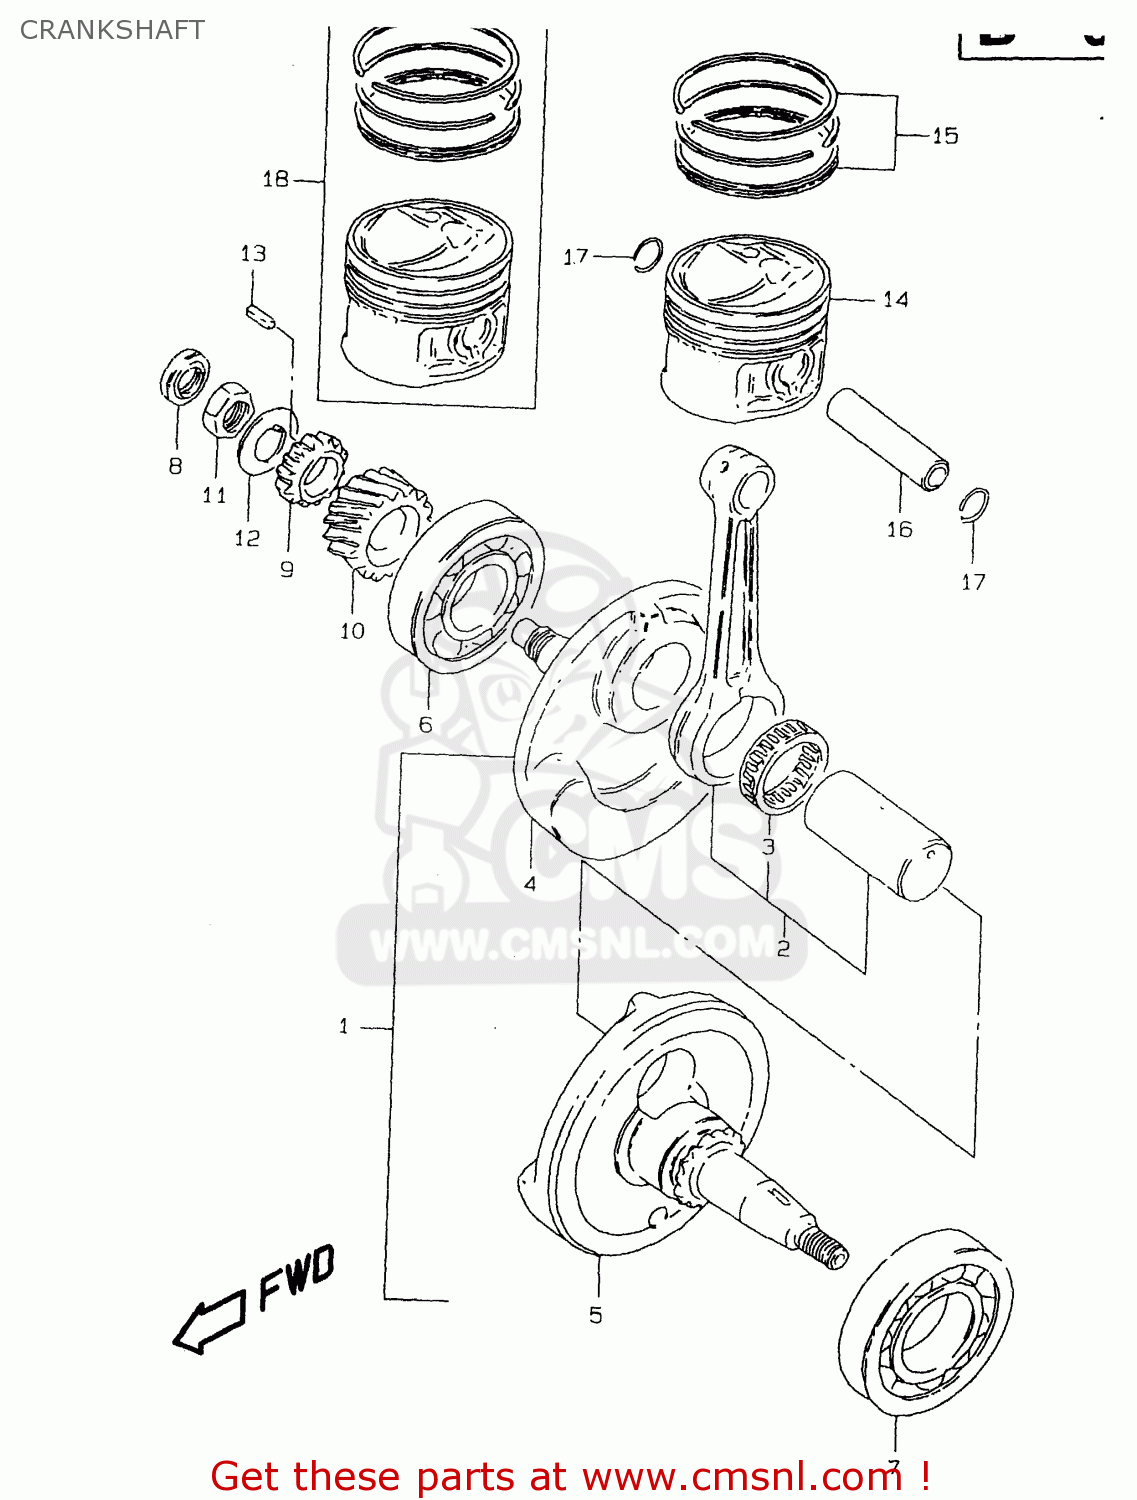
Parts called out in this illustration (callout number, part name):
1	CRANKSHAFT ASSY
2	CONNECTING ROD SET
3	BEARING(28X36X15.8)
4	CRANKSHAFT,R
5	CRANKSHAFT,L
6	BEARING(28X68X18)
7	BEARING(35X72X17)
8	SEAL,OIL(12X21X7)
9	GEAR,OIL PUMP DRIVE
10	GEAR,PRIMARY DRIVE
11	NUT
12	WASHER
13	KEY
14	PISTON
15	RING SET,PISTON
16	PIN,PISTON
17	RING,SNAP 14MM
18	PISTON SET(OS:0.5)
